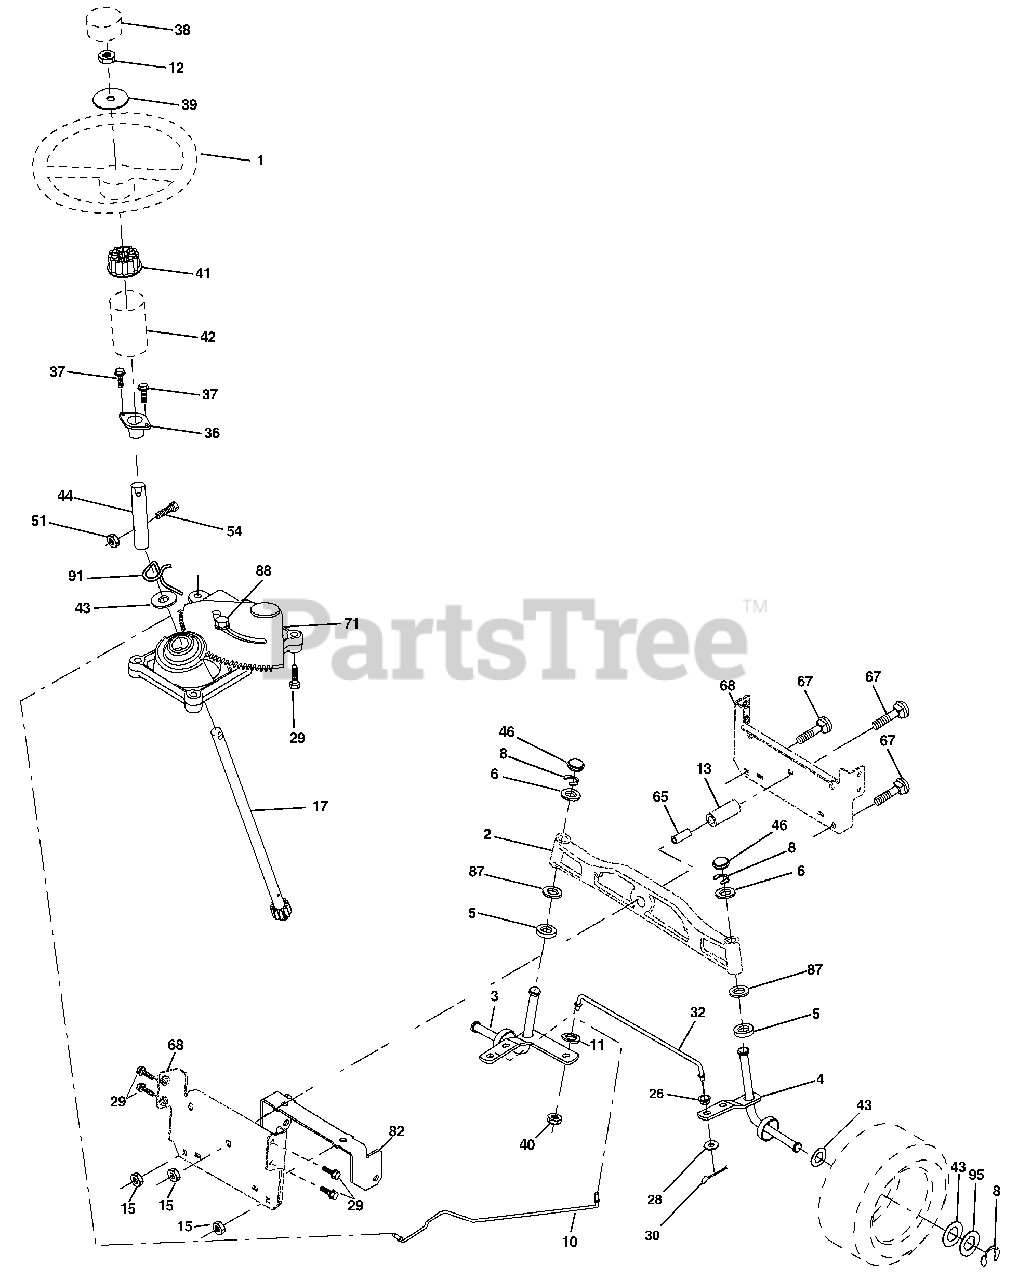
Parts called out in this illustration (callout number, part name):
1	Wheel Steering
2	Axle Asm Cast Iron LT
3	Spindle Asm LH
4	Spindle Asm RH
5	Bearing Race Thrust Harden
6	Washer 25/32 x 1-5/8 x 16 Ga.
8	Ring Klip #t5304-75
10	Link Drag
11	Washer Lock Hvy Hlcl Spr 3/8
12	Nut Hex Jam Toplock 1/2-20 unf
13	Spacer Brg Axle Front
15	Nut Hex Flange Lock
17	Shaft Asm Steering
26	Bushing Link Drag
28	Washer 13/32 x 7/8 x 16 Ga.
29	Screw 3/8-16 x .75
30	Pin Cotter 1/8 x 3/4
32	Rod Tie
36	Bushing Strg
37	Screw
38	Insert Cap Strg Wh
39	Washer 9/16 x 1 1/20 x 11 Ga.
40	Crownlock nut
41	Adaptor Wheel Strg
42	Boot Steering Dash
43	Washer 25/32 x 1 1/4 x 16 Ga.
44	Extension Steering Shaft
46	Cap Spindle Fr Top Blk
51	Nut Crownlock 1/4-28
54	Bolt Hex 1/4-28 unf x 1-1/4 Gr. 8
65	Spacer Brace Axle
67	Bolt RDHD SQNK 3/8-16 x 2 1/4
68	Axle, Brace
71	Steering Asm
82	Bracket Susp Chassis Front
87	Washer Flat .781 x 1-1/2 x .14
88	Bolt Shoulder 7/16-20 unc
91	Clip Steering
95	Washer Harden .739 x 1.637 x 060
